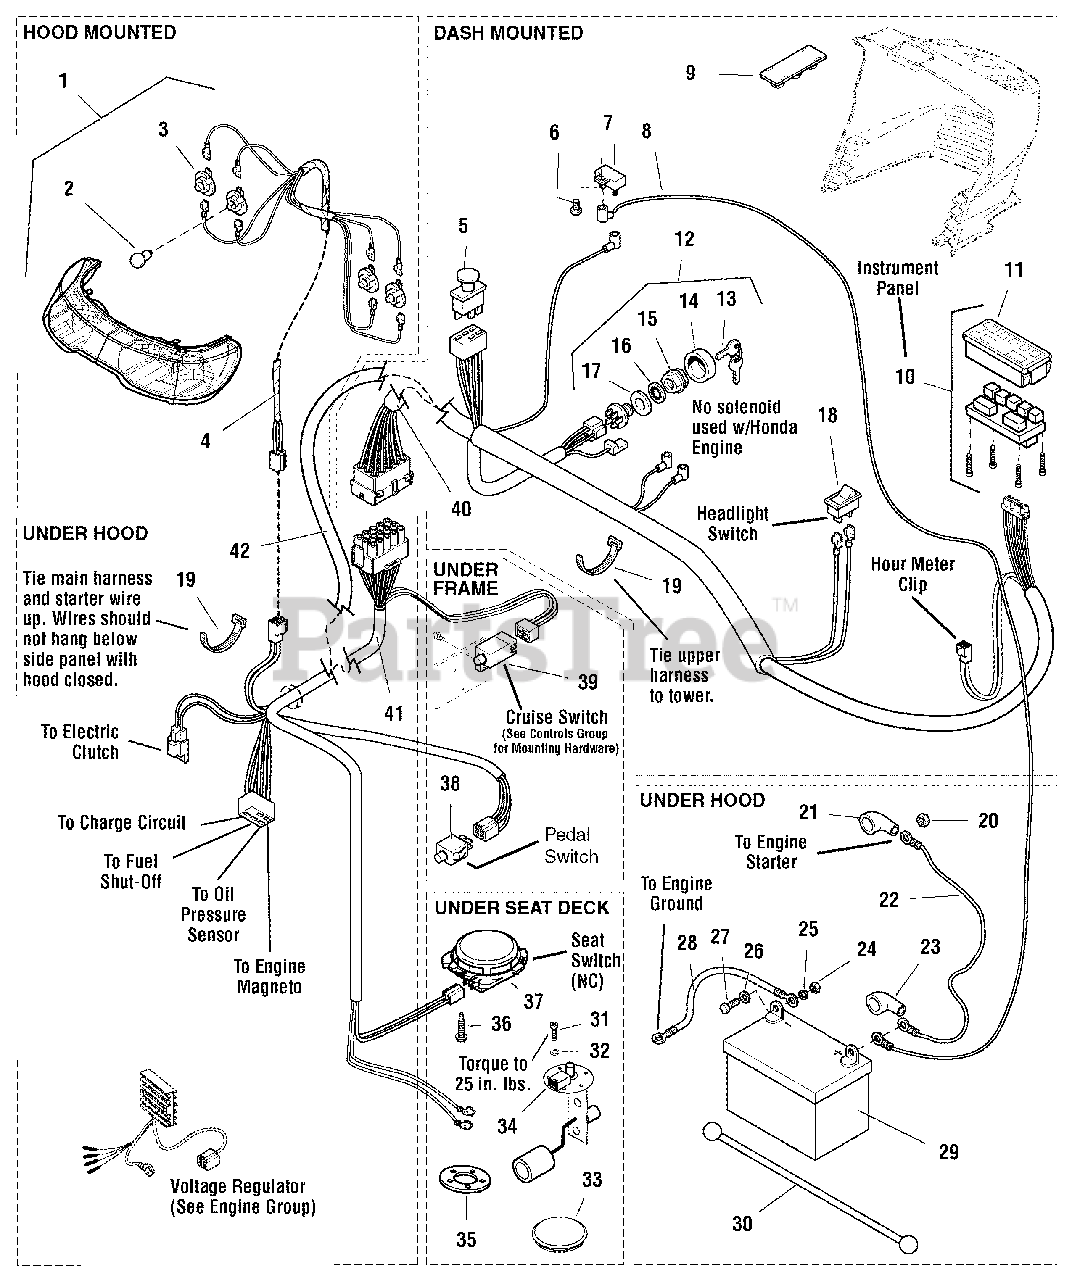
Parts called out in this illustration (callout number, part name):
1	HEADLIGHT ASSEMBLY, 4 Blub, (Incudes Ref. Nos. 2 & 3)
2	BULB, Headlight, 12.8V
3	SOCKET ASSEMBLY, Headlight, Sealed
4	HARNESS, Headlight
5	SWITCH, PTO Push/Pull Symbols
6	CAPSCREW, Hex Washer Head Taptite, 1/4-20 x 1/2, Black
7	BREAKER, Circuit, 12 Volt 20 Amps
8	WIRE, 12GA, 11" Long, Red
9	PLUG, Hole, Square
10	PANEL, Instrument w/ Fuel Gage & Hour Meter (Includes Ref. No. 11)
11	COVER, Instrument Panel
12	SWITCH ASSEMBLY, Ignition 5/8-32, 6 Pin, (Includes Ref. Nos. 13, 14, 15, 16 & 17)
13	KEYS, Set of 2
14	COVER, For Ignition Switch, Plastic
15	NUT, Hex Flange, 5/8-32, Ignition Switch
16	LOCKWASHER, Internal Tooth, 5/8, Thin
17	WASHER, Shim
18	SWITCH, Headlights , 2 Terminal
19	TIE, Strap, 7-5/16" Long
20	NUT, Hex Flange, M08-1.25
21	BOOT, Insulator Cable Terminal, 1-15/16 Long, Red
22	CABLE, #6 x 25" Long, Ring Terminals
23	BOOT, Insulator Battery Terminal
24	NUT, Hex, 1/4-20
25	LOCKWASHER, 1/4
26	WASHER, 1/4
27	CAPSCREW, Hex Head, 1/4-20 x 3/4
28	CABLE, #6 x 26 Long, Ring Terminal
29	BATTERY, 12VOLT
30	STRAP, Battery, 14 Long, Rubber
31	SCREW, Truss Head Phillips, #10-32 x 1/2
32	LOCKWASHER, 3/16 #10
33	PLUG, Hole 3", Round
34	SENDER, Fuel Tank
35	GASKET, Fuel Sending Unit
36	CAPSCREW, Hex Washer Head Plastite, 1/4 x 1/2
37	SWITCH, Seat, Grey, NC
38	SWITCH, Push Button, Foot Pedal
39	SWITCH, Cruise Control, Grey, NO
40	HARNESS, Wiring Upper (Units with 2 Piece Harness)
41	HARNESS, Wiring Lower (Units with 2 Piece Harness)
42	HARNESS, Wiring (Units with 1 Piece Harness)
